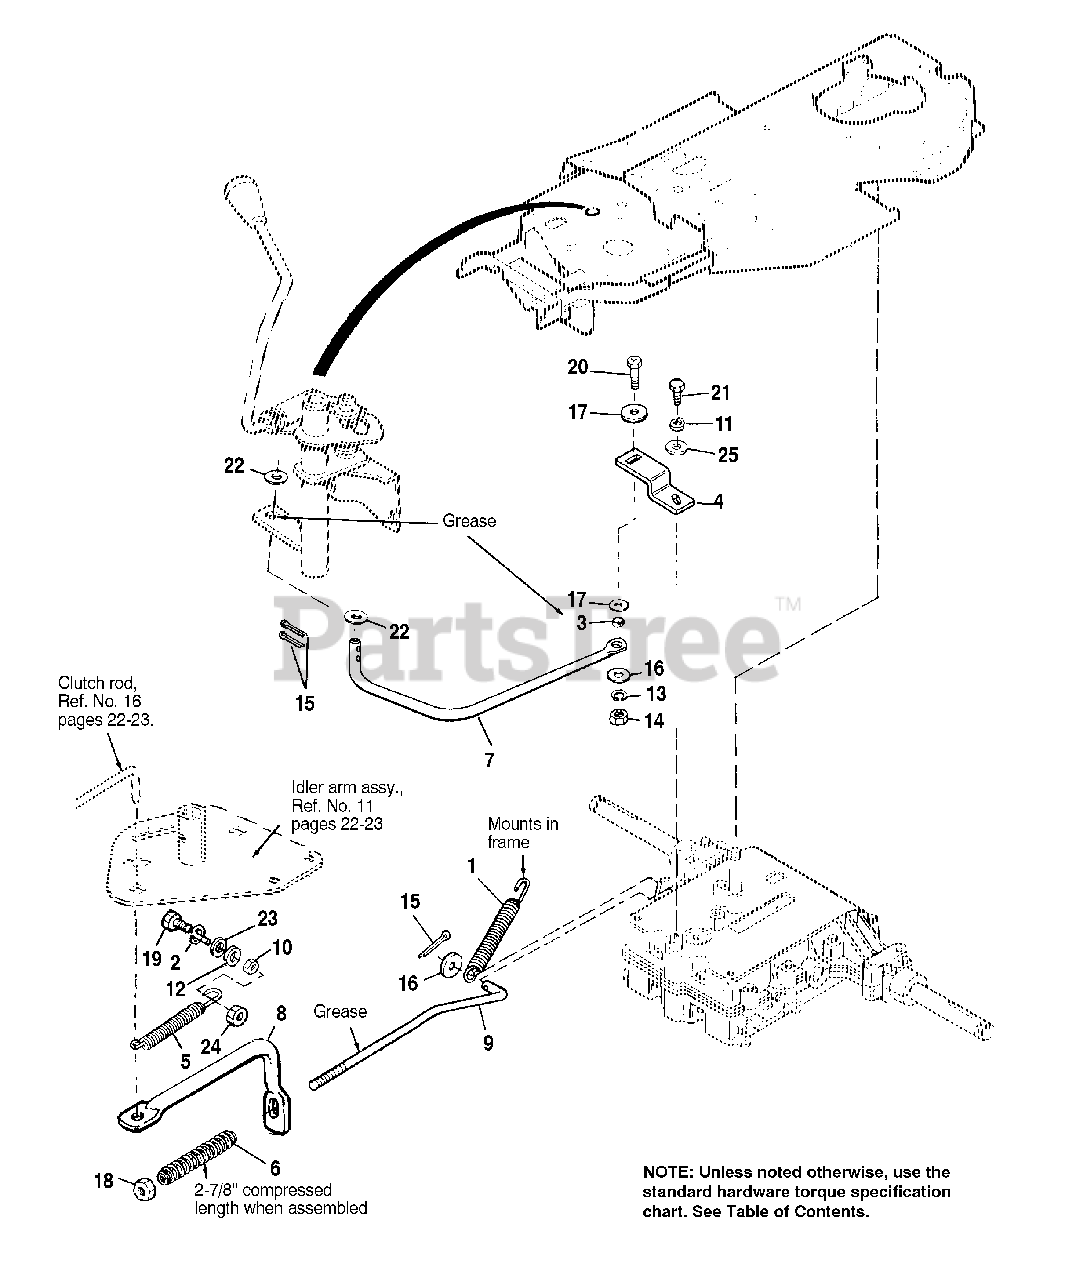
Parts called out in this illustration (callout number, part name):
1	SPRING, External
4	LEVER, Shift
5	SPRING, External
6	SPRING, Compression
7	ROD, Shift
8	GUIDE, Brake Rod
10	NUT, Hex, 3/8-16
11	LOCKWASHER, 1/4
12	LOCKWASHER, Spring, 3/8
13	LOCKWASHER, 5/16
14	NUT, Hex, Full, 5/16-18
15	COTTER PIN, 3/32 x 3/4
16	WASHER, Plain, 5/16
17	WASHER
18	NUT, Nylon Lock, 5/16-18
19	CAPSCREW, Hex Hd., 3/8-16 x 1-1/2
20	CAPSCREW, Hex, 5/16-18 x 1-1/4
21	CAPSCREW, Hex, 1/4-28 x 5/8
22	WASHER, 1/2
23	WASHER, 3/8
24	JAM NUT, Centerlock, 3/8-16
25	WASHER, Plain, 1/4
